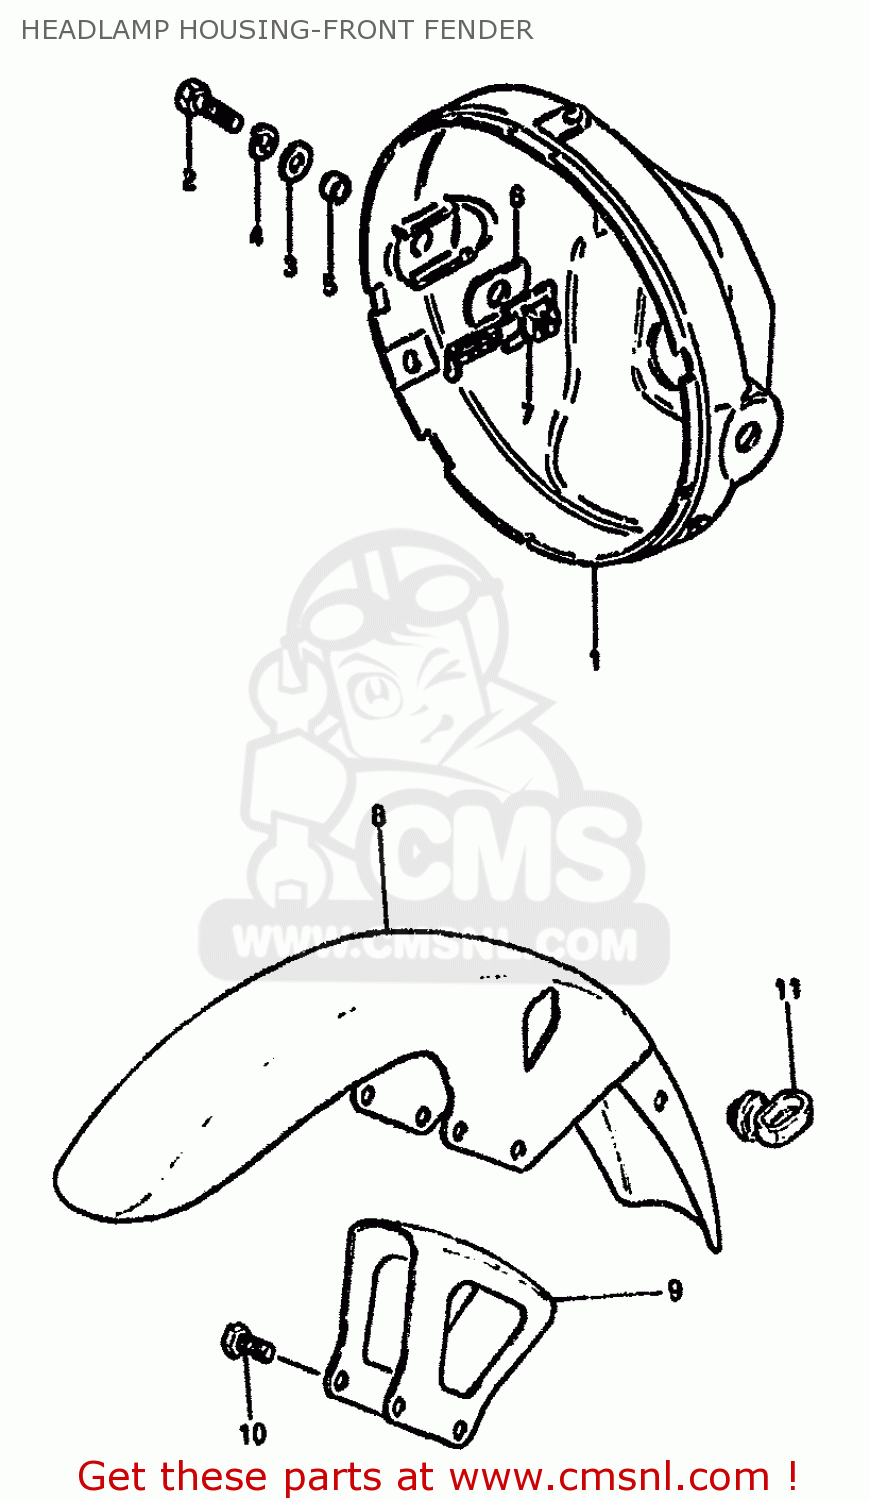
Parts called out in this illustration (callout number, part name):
1	HOUSING,HEADLAMP
2	BOLT
3	WASHER
4	LOCK WASHER
5	SPACER (8.8X12X7)
6	CUSHION
7	PLATE,HEADLAMP HOUSING
8	FENDER,FRONT
9	BRACE,FRONT FENDER
10	BOLT 8X16
11	GUIDE,CABLE
